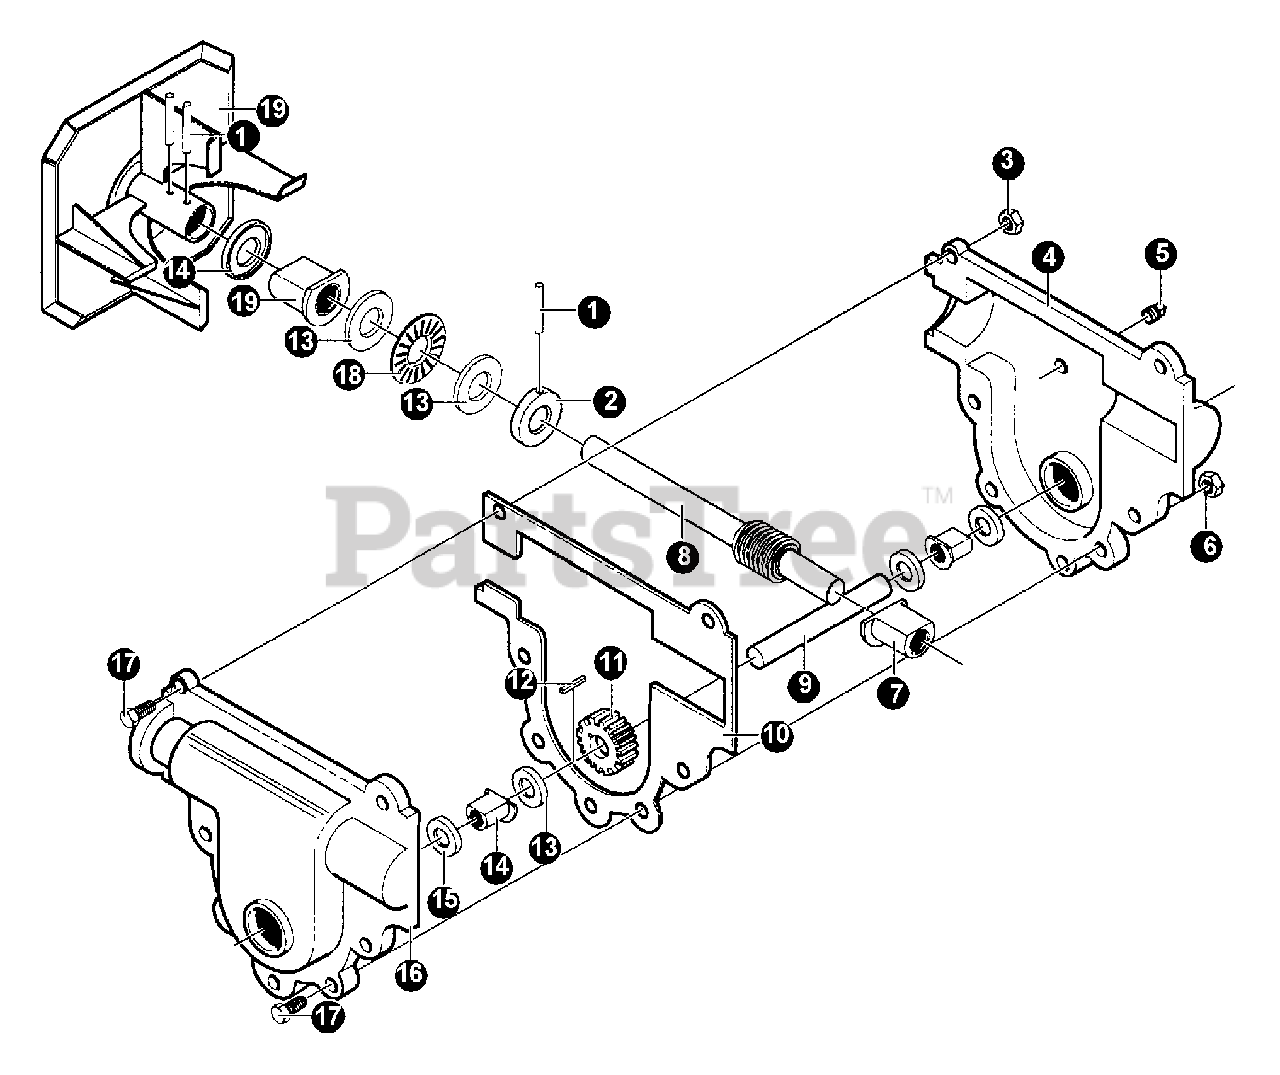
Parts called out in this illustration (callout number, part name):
1	PIN, SPRING
2	COLLAR, THRUST 0.753×1.24×0.50
3	NUT
4	CASE, GEAR - LEFT
5	SCREW 3/8"-16
6	NUT, 1/4"-20
7	BEARING, FL 0.502IDX0.752ODX0.75
8	SHAFT, WORM
9	SHAFT, AUGER OUTPUT
10	GASKET, GEAR CASE
11	GEAR, WORM
12	KEY, WOODRUFF #61
13	WASHER, FLAT
14	BEARING, FL 0.752IDX1.002OD
15	SEAL, OIL
16	CASE, GEAR - RIGHT
17	SCREW 1/4 - 20×75 HHC
18	BEARING, ROLL
19	IMPEL ASSY
